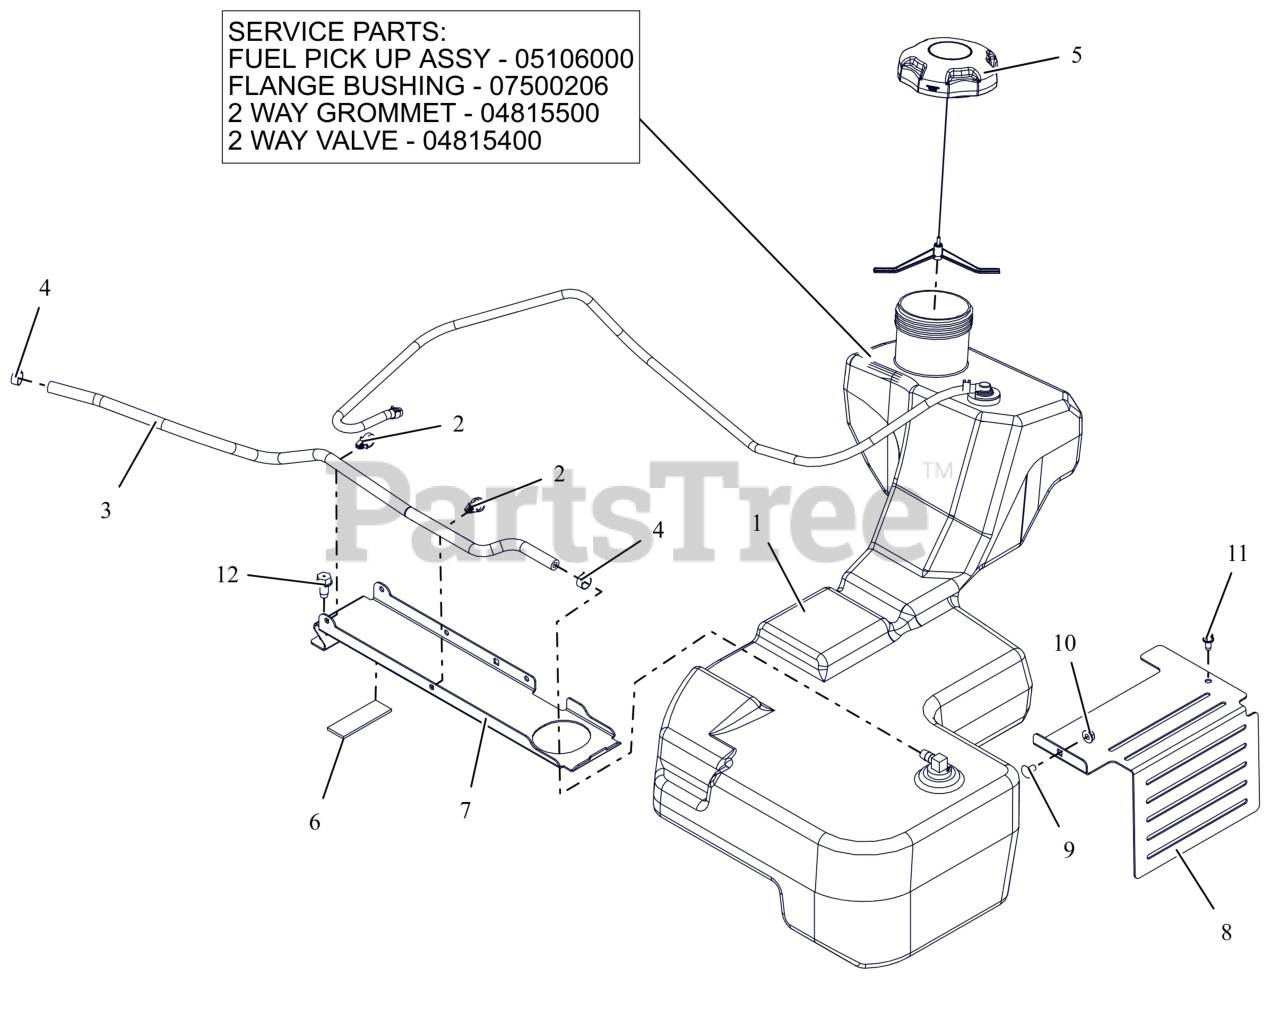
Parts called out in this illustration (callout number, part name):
1	ASM, FUEL TANK-HD
1	ASM, HD FUEL PICK-UP
1	BSHG-FLG .375X1.062X.625 NITR
1	GROMMET, 2-WAY
1	VALVE, 2-WAY
2	ROUTING CLIP (1/2" ID)
3	HOSE, .25 LOW-PERM BULK GAS
4	CLAMP, FUEL LINE
5	CAP, FUEL - 3.50 RATCHET INLET VENT
6	PAD,RBR 1.0"X3.0" W/ADHESIVE
7	BRKT, FUEL TANK HOLD DOWN
8	GUARD, TRANSAXLE FAN LH (BLACK)
9	BLT, RHSSN.25-20X.500 G5 ZCC
10	NUT-LK-CTR-FLG .25-20 ZC120
11	SCR-TAP .25-20X.50 HWH ZCC
12	SCR,TAP .375-16X.75 HWH TR ZCC
